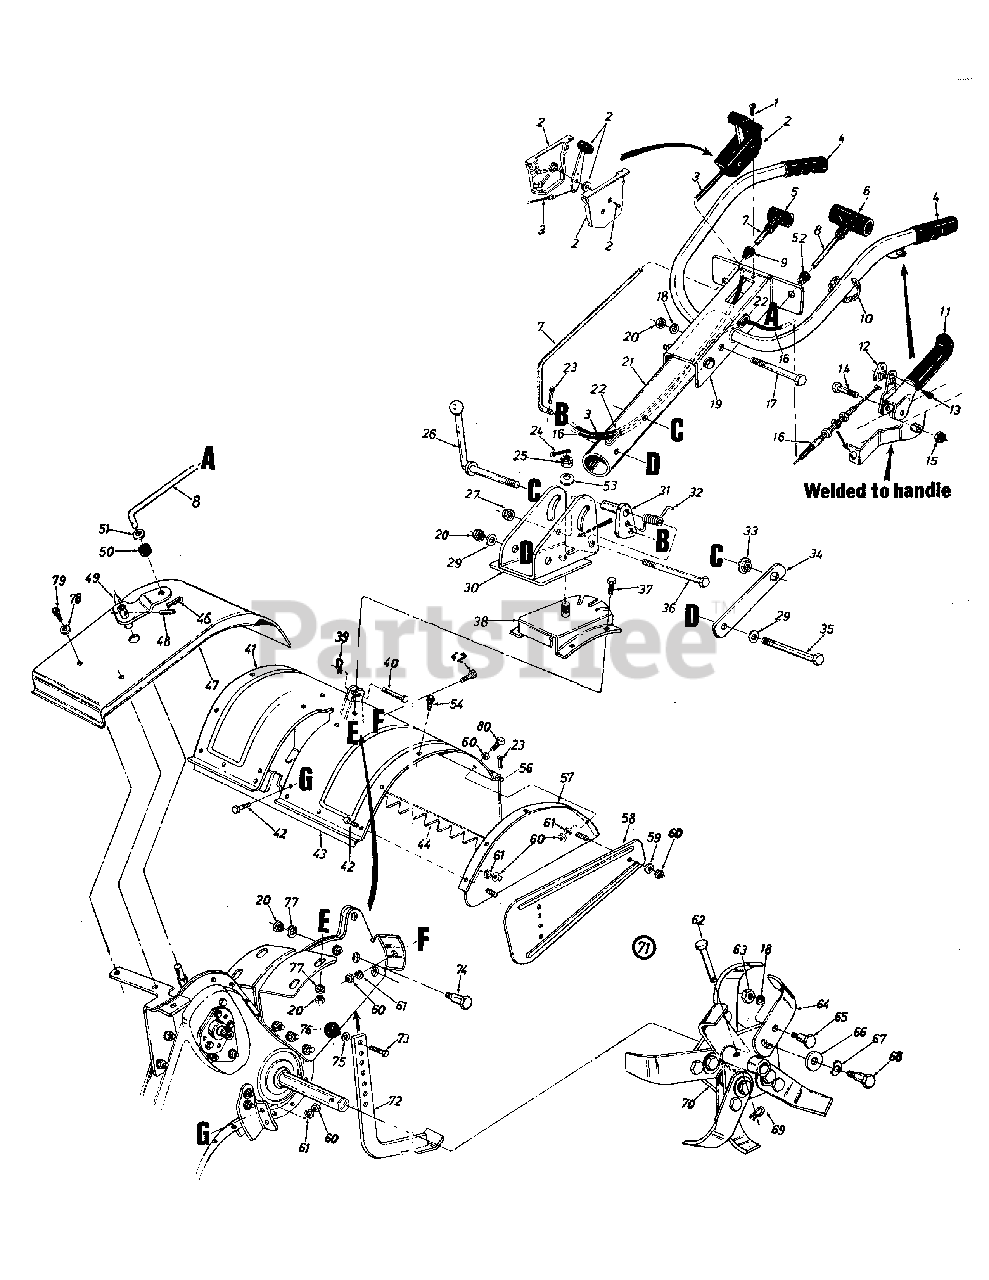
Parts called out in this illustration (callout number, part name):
1	Truss Mach. AB-Tap. Scr. #10 x .50" Lg.
2	Throttle Control Box Ass'y.
3	Throttle Control Wire
4	Handle Grip
5	Small "T" Knob
6	Large "T" Knob
7	Clutch Rod
8	Control Rod 37" Lg.
9	Snap On Bushing 3/8" Dia.
10	Cable Tie-Self Clinching
11	Clutch Grip Ass'y. - L.H.
12	Barrel Cable Hold Down
13	Hex B-Tap Scr. #10 x .44" Lg.
14	Hex Bolt 3/8-24 x 2.25" Lg.
15	Hex Jam L-Nut 3/8-24 Thd.
16	Clutch Control Cable 46" Lg.
17	Hex Bolt 3/8-16 x 3.00" Lg.
18	L-Wash. 3/8" I.D. - H.D.
23	Cotter Pin 3/32" Dia. x .75" Lg.
24	Cotter Pin 3/32" Dia. x 1.25" Lg.
25	Hex Slotted Nut 5/8-18 Thd.
26	Handle Adj. Crank
27	Hex Cent. L-Nut 3/8-16 Thd.
29	Bell-Wash. .4" I.D. x .87" O.D.
30	Handle Pivot Bracket
31	Positioner Crank Ass'y.
32	Spring Handle Adj. (Torsion)
33	Hex Flange Nut 3/8-24 Thd.
34	Bracket Hex Nut Retainer
35	Hex Bolt 3/8-16 x 3.25" Lg.
36	Hex Bolt 3/8-16 x 3.00" Lg. - Gr. 8
37	Hex Bolt 3/8-16 x 1" Lg.
40	Clevis Pin .375" Dia.
43	Bracket Reinforcement - 18"
46	Intern. Cotter Pin 5/16" Dia.
49	Shifting Crank Ass'y.
50	Rubber Washer .33" I.D.
51	Fl-Wash. .4" I.D. x 1.25" O.D.
52	Snap On Bushing 1/2" Dia.
53	Bell-Wash. .63" I.D. x 1.25"
54	Hex Wash. Tap Scr.
56	Tiller Flap Rod
57	End Cover Ass'y.
60	Hex Nut 5/16-18 Thd.
61	L-Wash. 5/16" I.D.
62	Clevis Pin .375" Dia.
63	Hex Nut 3/8-24 Thd.
64	13" Dia. Articulating Tine
65	Shld. Bolt 1/2" Dia. x .175
66	Fl-Wash. .51" I.D. x 1.50"
67	Bell-Wash. .515" I.D. x 1.14"
68	Shld. Bolt 1/2" Dia. x .320
69	Intern. Cotter Pin
70	Tine Adapter Ass'y. 18"
71	Tine Ass'y. Comp. 18"
72	Depth Bar Ass'y.
73	Hex Bolt 3/8-16 x .75" Lg.
74	Shld. Bolt 1/2" I.D. x .62" Lg.
75	Fl-Wash. 3/8" I.D. x 5/8" O.D.
76	Ball Knob
77	L-Wash. 3/8" I.D.
78	Fl-Wash. .281" I.D. x .62"
79	Hex Wash. Self-Tap Scr. 1/4-20 x .50" Lg.
80	Hex Bolt 5/16-18 x 1-1/4" Lg.
81	Fl-Wash. .344" I.D. x .62 O.D.
